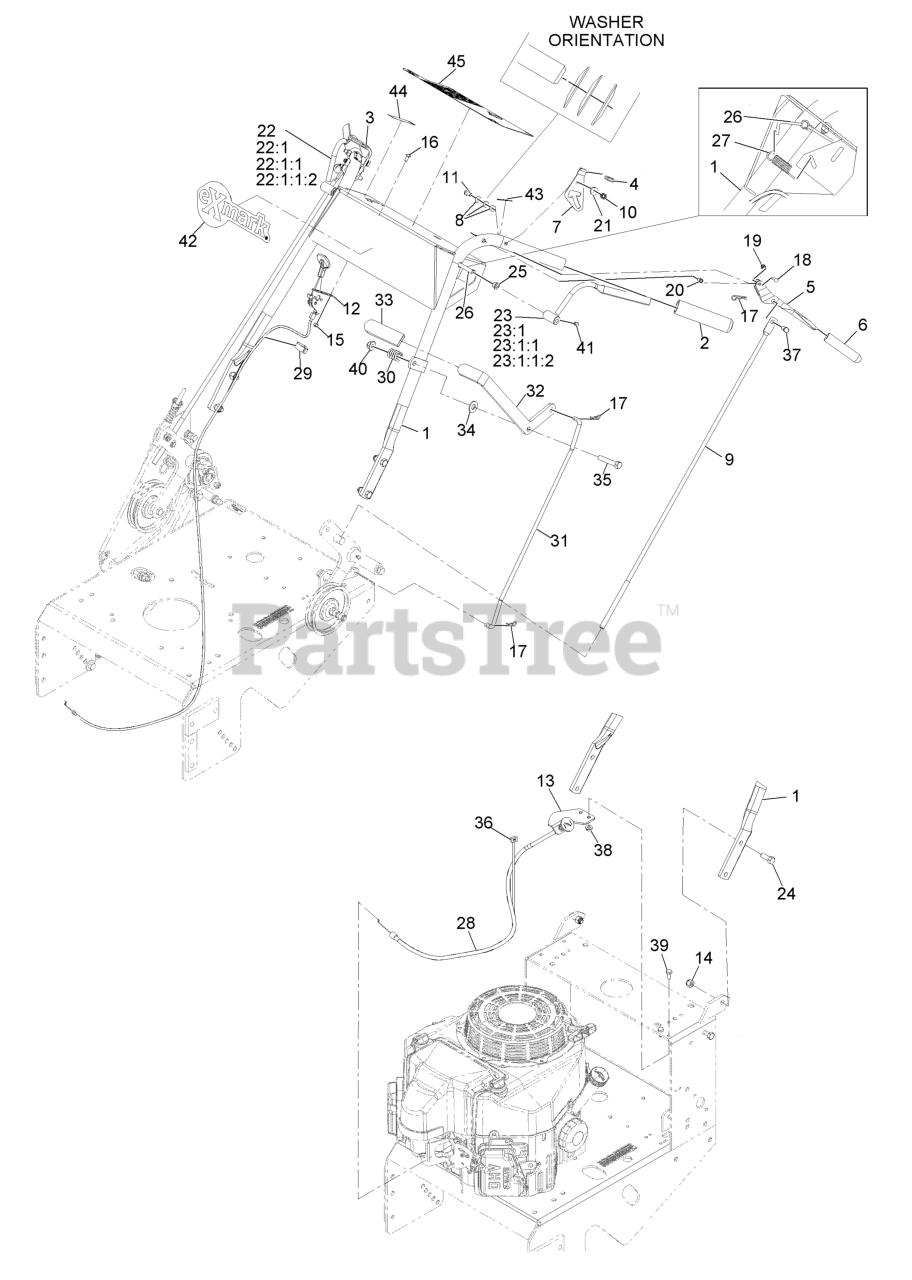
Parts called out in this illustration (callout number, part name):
1	Wld,Handle Metro
1	KIT,HANDLE W/DECALS METRO
2	GRIP-FOAM
4	GRIP-LATCH
5	DRIVE LEVER ASM
6	GRIP-LEVER, DRIVE
8	WASHER-SPRING
9	LINKAGE-WHEEL, DRIVE
10	NUT-LOCK, NI
11	SCREW-HH
12	CONTROL, THROTTLE
13	BRACKET-CABLE, CHOKE
14	NUT-LOCK, NI
15	NUT-LOCK, NI
16	BOLT-CARR
17	PIN-COTTER
18	PIN-LEVER, DRIVE
19	NUT-PUSH
20	PIN-ROLL
22	LEVER-RH
22:1	Lever
22:1:1	ASM,Hub/Setscrew
22:1:1:2	SCREW-SET
23	LEVER-LH
23:1	Lever
23:1:1	ASM,Hub/Setscrew
23:1:1:2	SCREW-SET
24	SCREW-HH
25	BUSHING-NYLON
26	WLD,ROD OPC
27	SPRING-EXTENSION
28	CABLE-CHOKE
29	CLIP-CABLE
30	SPRING-COMPRESSION
31	LINKAGE-BLADE, UPPER
32	LEVER ASM
33	GRIP-LEVER
34	WASHER-FLAT
35	SCREW-HH
36	TIE-PLASTIC
37	PIN-CLEVIS
39	SCREW-HH
40	NUT-HF, NI
41	SCREW-SET
42	DECAL,EXMARK LOGO
43	DECAL-NEUTRAL BRAKE
44	DECAL-THROTTLE
45	DECAL-CONSOLE METRO PG
